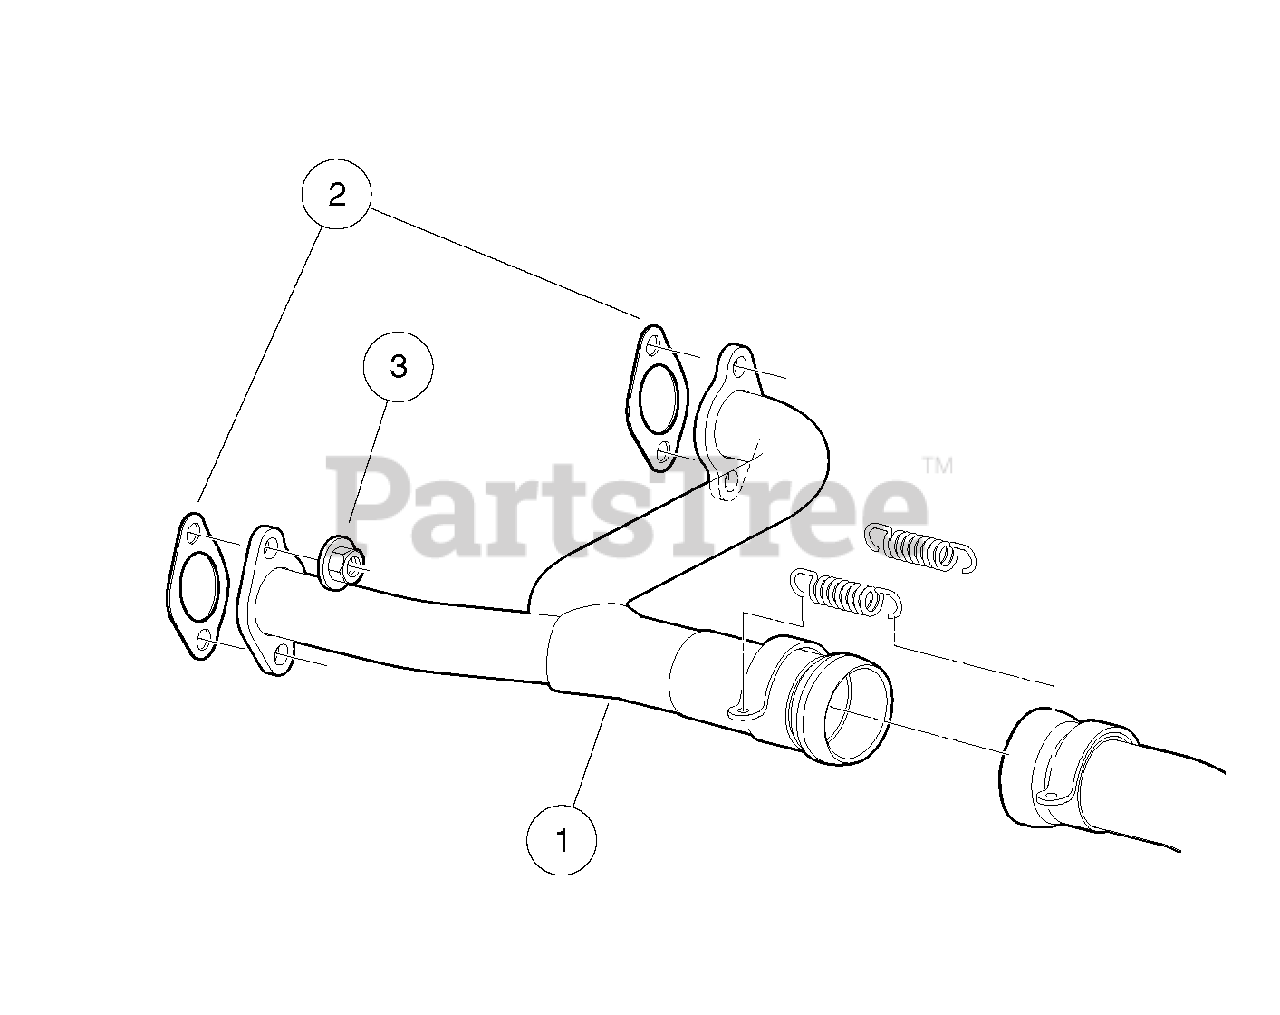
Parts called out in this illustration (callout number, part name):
1	Header, Exhaust, Gas
2	Gasket, Exhaust, Gx620
3	Nut Flg, M8 X 1.25 Serrated
